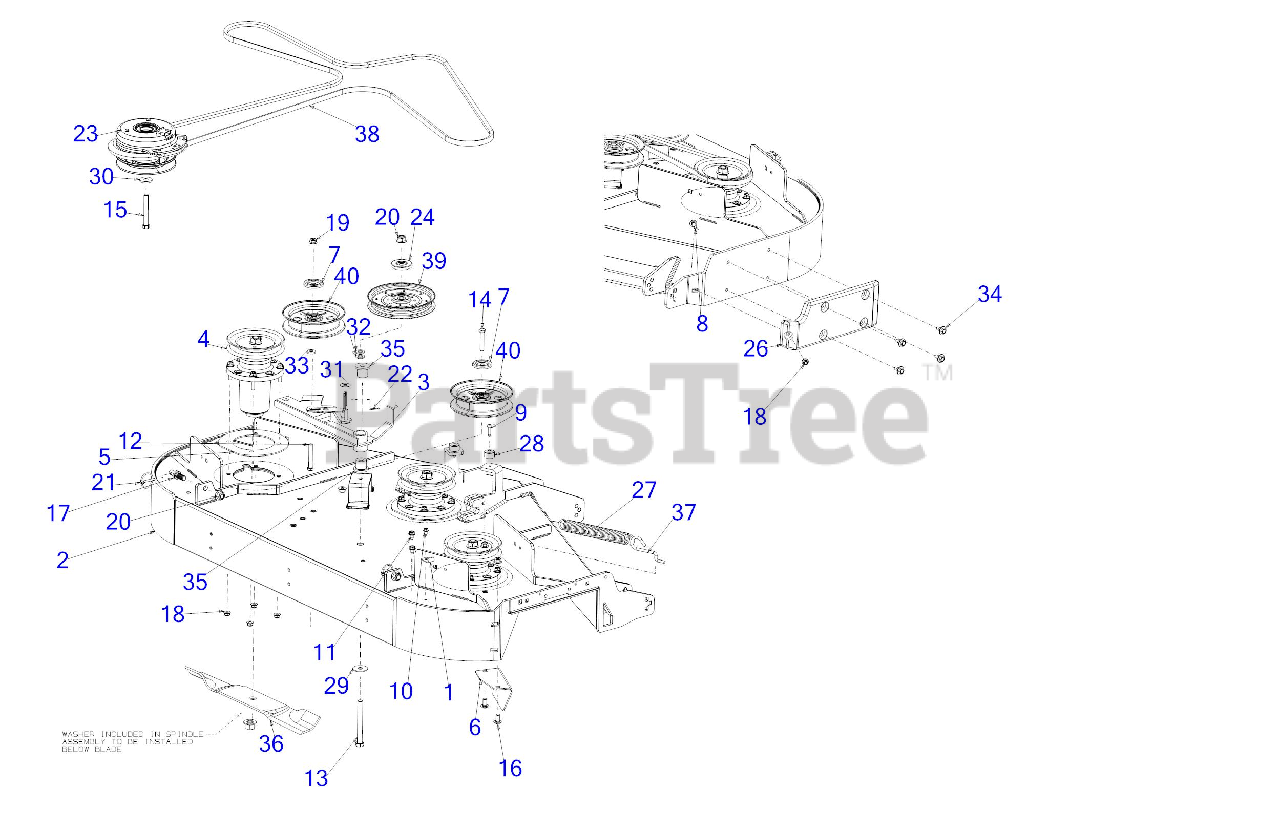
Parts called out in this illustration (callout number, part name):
1	HOOK RETAINER BRACKET
3	DECK IDLER ASSEMBLY
4	SPINDLE ASSEMBLY
4	Cub Cadet 54" SPINDLE ASSEMBLY (07416)
7	PULLEY CAP 1.875 DIA
8	CARRIAGE BOLT 5/16-18 x 1.00
9	SCREW 1/4-20 x 1.0
10	SCREW 1/4-20 X.500
11	SCREW 5/16-18 x .500
12	HEX SCREW-3/8-16X2.5 GR5
13	SCREW 1/2-13 x 4.5 GR 5
14	SCREW 3/8-16 x 2.0 GR5
15	SCREW 7/16-20 x 3.25 GR5
16	CARRIAGE BOLT 3/8-16 x .75
18	FLANGE LOCK NUT 5/16-18
22	COTTER PIN 3/32
23	ELECTRIC PTO CLUTCH
24	PULLEY CAP 1/2"
26	DECK SKID PLATE (LH)
27	EXTENSION SPRING
29	WASHER .51 x 1.5 x .07
30	FLAT WASHER .445 x 1.248 x .170
31	FLAT WASHER
32	FLAT WASHER
33	FLAT WASHER
34	SHOULDER SCREW .43X.29X5/16-18 TT
35	SHOULDER SPACER
36	19" BLADE (HI LIFT)
36	Cub Cadet 54" HI LIFT BLADE SET
36	LOW-LIFT 19"BLADE (54"DECK)
36	BLADE- HI LIFT 19.0 XTREME
36	BLADE-19"MULCH 54"
36	19" XTREME BLADE
37	DECK SPRING HOOK
38	V-BELT B SEC x 154
38	Cub Cadet 54"Z-FORCE DECK BELT (05013)
39	IDLER PULLEY 6.0" DIA
40	5" FLAT IDLER PULLEY
